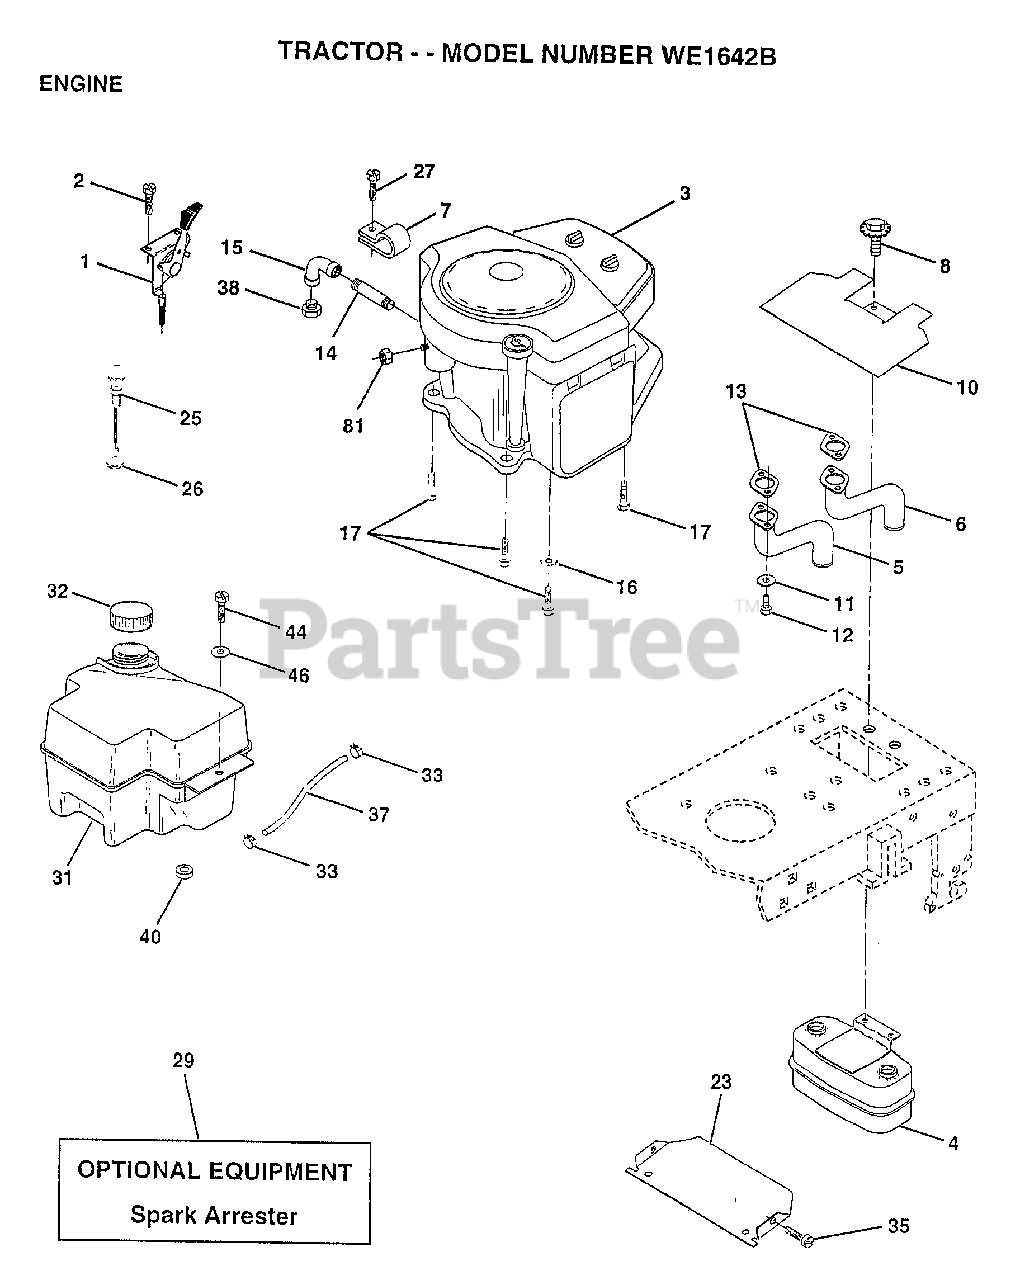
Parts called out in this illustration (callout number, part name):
1	CONTROL THRT 35.5
2	SCREW LT
3	ENGINE, BRIGGS
4	MUFFLER.TW.LOTONE
5	EXHAUST.B&S.18.LH
6	EXHAUST.B&S.18.RH
7	CLAMP.TUBE.DBL.EN
8	BOLT.5/16-18.UNC
10	SHIELD.HEAT.
11	LOCKWASHER
13	GASKET MUFFLER
14	PIPE NIPPLE LT
15	ELBOW
16	LOCKWASHER
17	SCREW LT
23	SHIELD-HEAT
25	CONTROL.CHOKE.37
26	"NUT,KEPS 3/8-24IM"
27	"SCREW-TT,10-32 FL"
32	CAP ASM FUEL
33	HOSE CLAMP
35	SCREW
37	LINE FUEL
44	SCREW HEX CRT
46	WASHER
81	NUT
